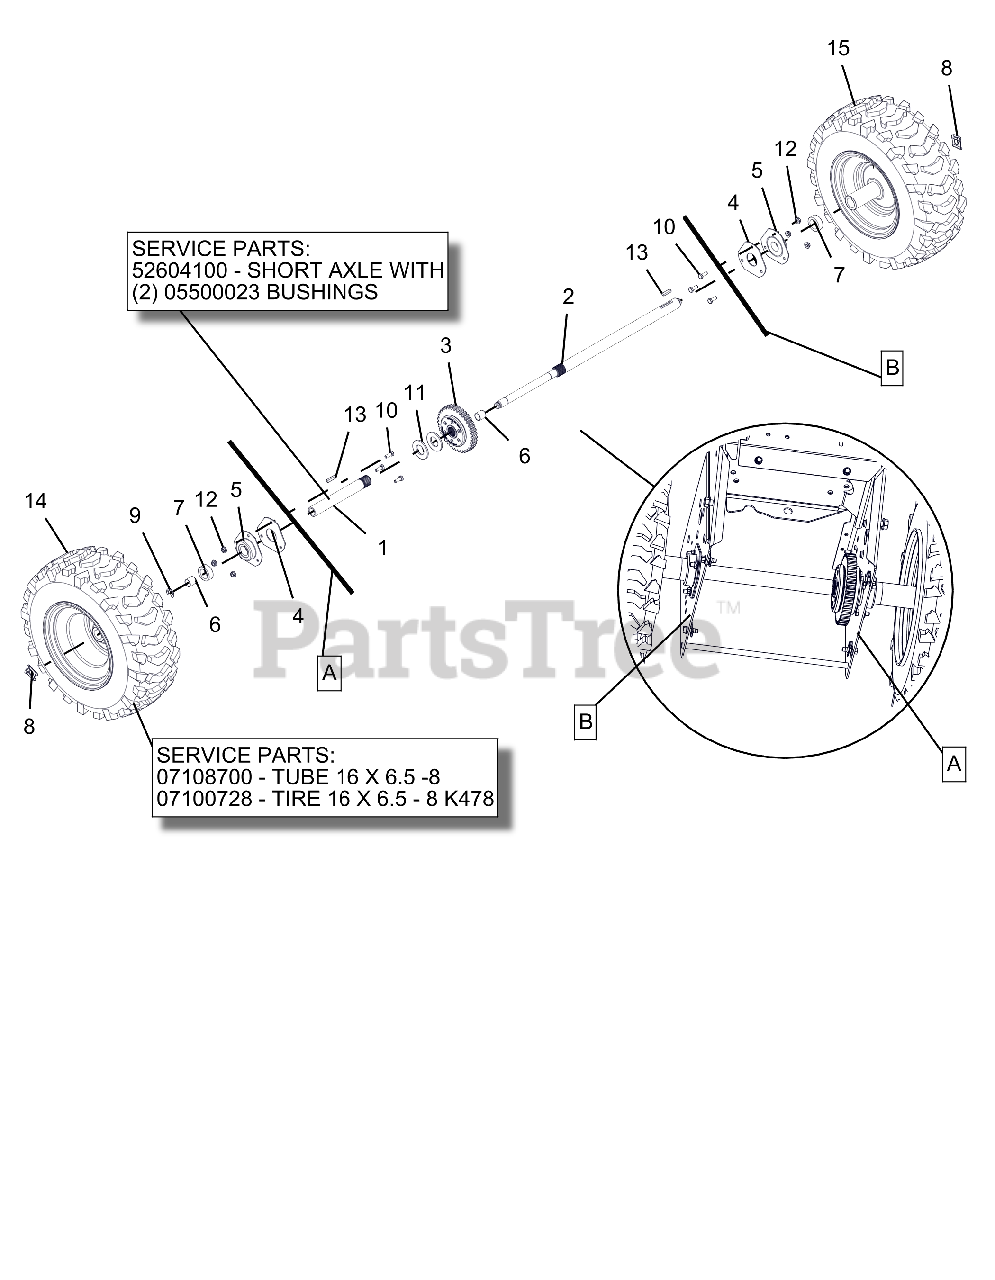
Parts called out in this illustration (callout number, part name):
1	AXLE, SHORT-PRO AUTO DIFF
1	BSHG-SLV .706X.764X.75 BRZ
1	AXLE, SHORT-AUTO W/BUSHINGS
2	AXLE, LONG-PRO AUTO DIFF
3	DIFFERENTIAL, AUTOMATIC
4	PLATE, BEARING SPACER
5	BRG-FLG 1.003/1.000 3 BOLT
6	BSHG-SLV .706X.764X.75 BRZ
7	SPACER, PRO AXLE BEARING
8	CLIP, SNAP .625 DIA
8	TUBE
8	TIRE, 16X6.50-8 K478
9	RG-RTNG-EXT .625X.042
10	@BLT-HEX .25-20X.75 GR5 YWZC
11	WSHR-FL-STL- 1.062X2.0X.134 YZ
12	@NUT-LK-CTR-FLG .25-20 YWZC
13	KEY-RECT .25X.188X1.00
14	TIRE/WHEEL, RH 16X6.50-8 DIFF
15	TIRE/WHEEL, LH 16X6.50-8 DIFF
